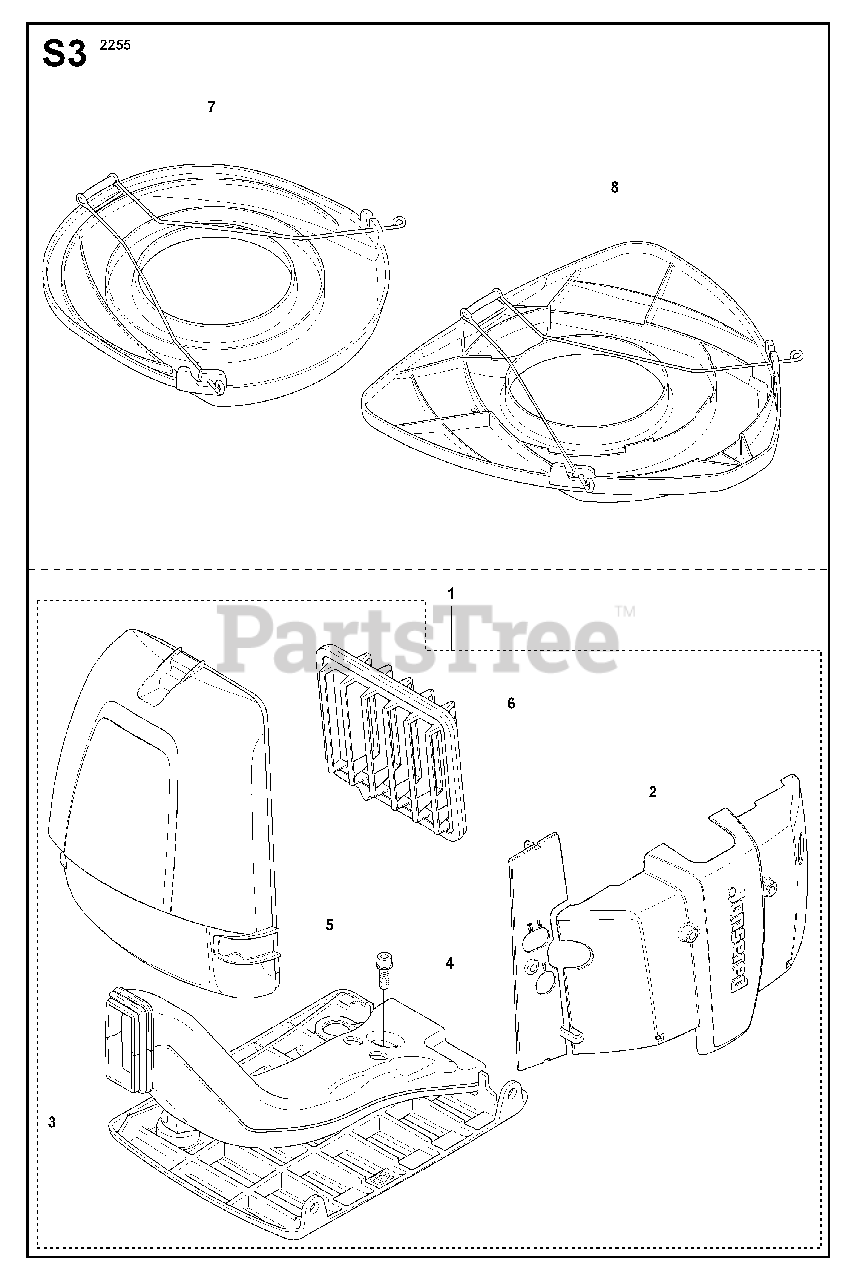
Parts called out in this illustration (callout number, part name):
6	FILTER
7	BLADE GUARD TRANSPORT
8	TRANSPORT GUARD
